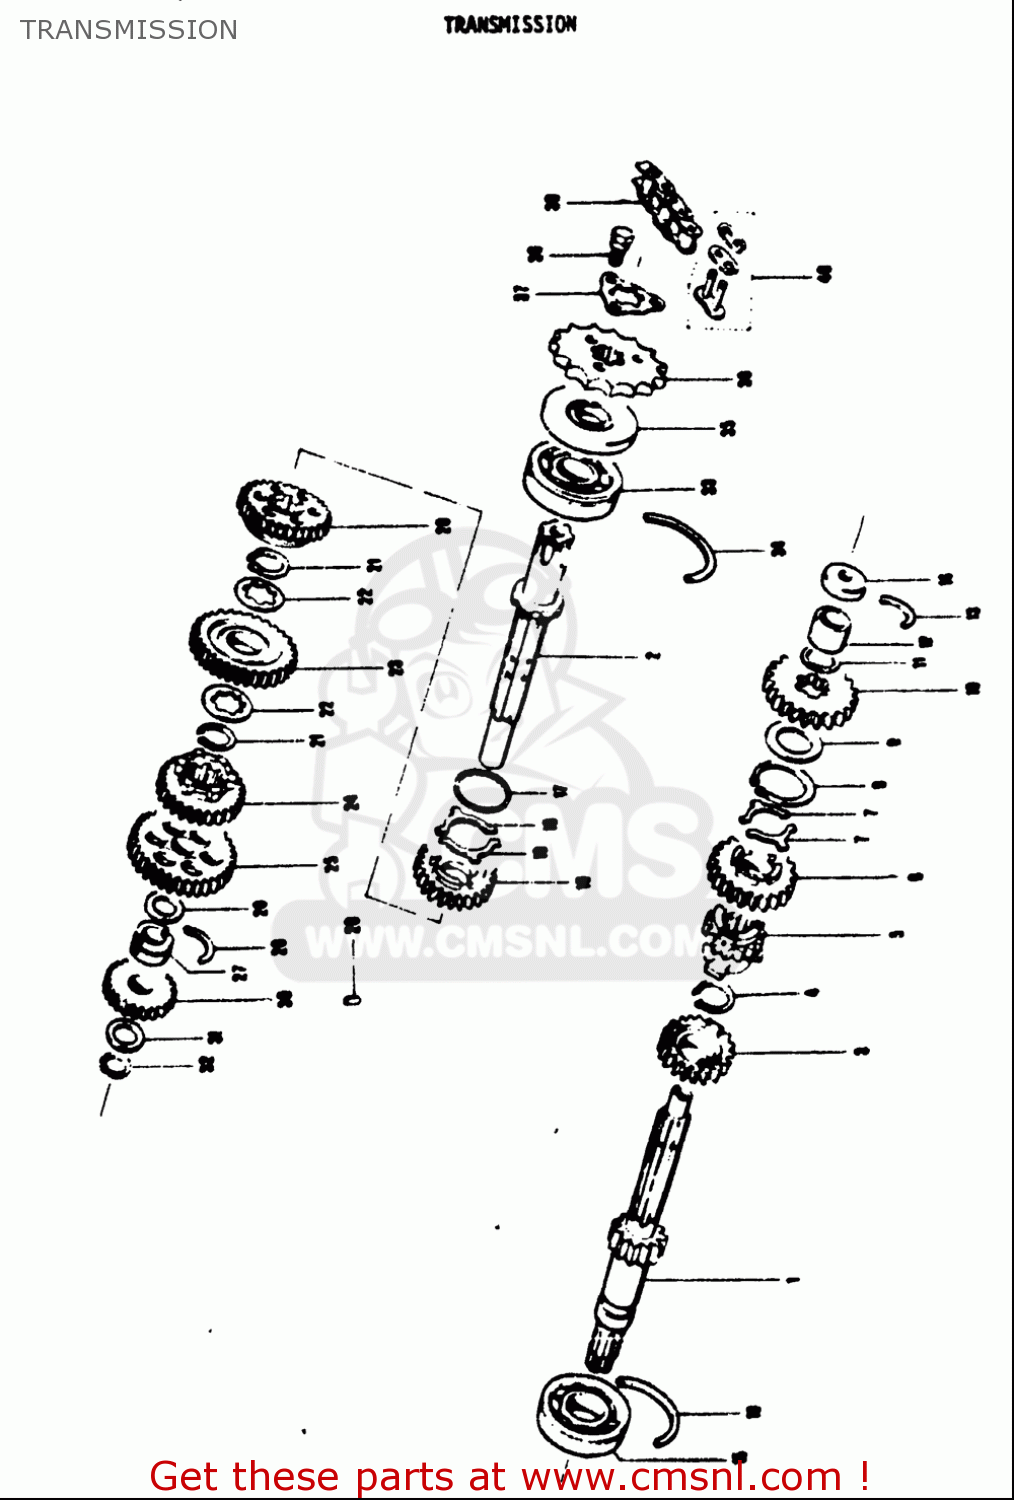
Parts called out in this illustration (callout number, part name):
4	CIRCLIP
8	RING,SNAP
9	WASHER
11	WASHER
12	BEARING(12X19X12)
14	SEAL,OIL(6X19X7)
17	CIRCLIP
21	CIRCLIP
22	WASHER,LOCK
26	SHIM, 15X24X1.0
29	PIN
32	CIRCLIP
33	BEARING(20X52X15)
35	SEAL,OIL (20X52X7)
36	SPROCKET,ENGINE(NT:16)
38	BOLT
